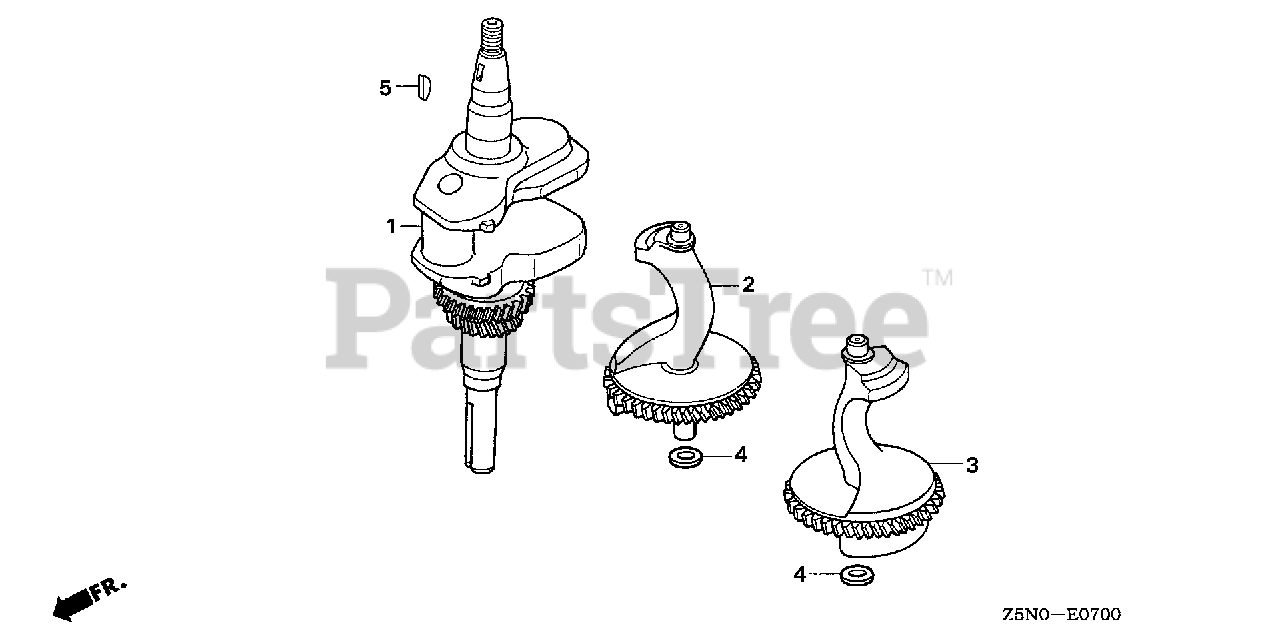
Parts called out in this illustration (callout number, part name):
1	CRANKSHAFT
2	WEIGHT A, BALANCER
3	WEIGHT B, BALANCER
4	WASHER, THRUST (15MM)
5	KEY, SPECIAL WOODRUFF (25X18)
